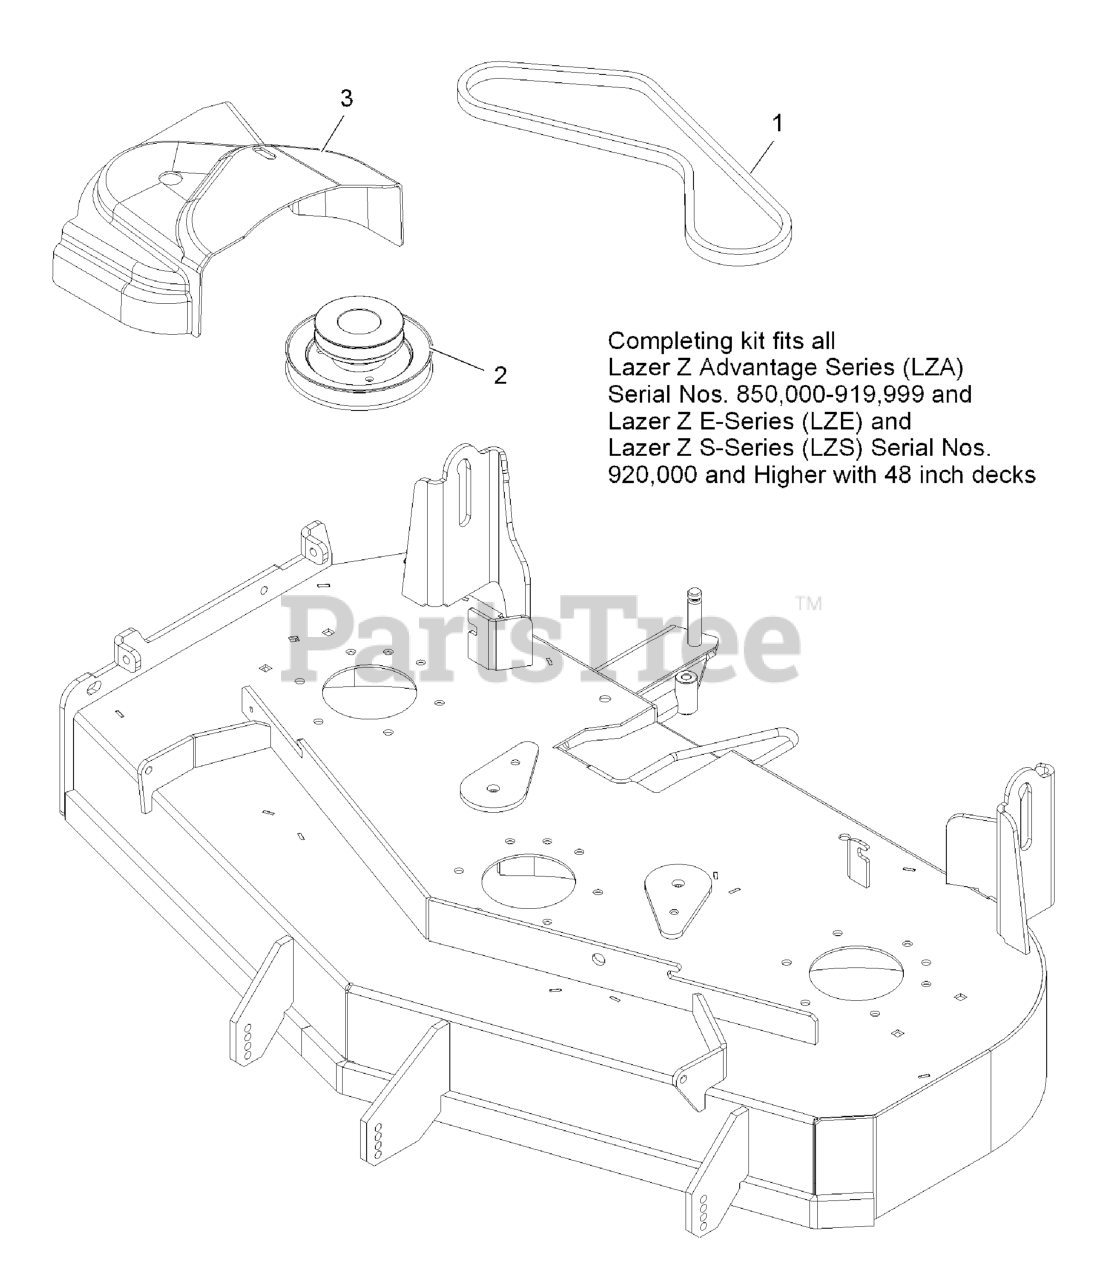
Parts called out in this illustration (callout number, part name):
1	BELT-BLOWER
2	JACKSHAFT-UV DRIVE, 484 SPLINED
3	COVER,BELT UV 48
